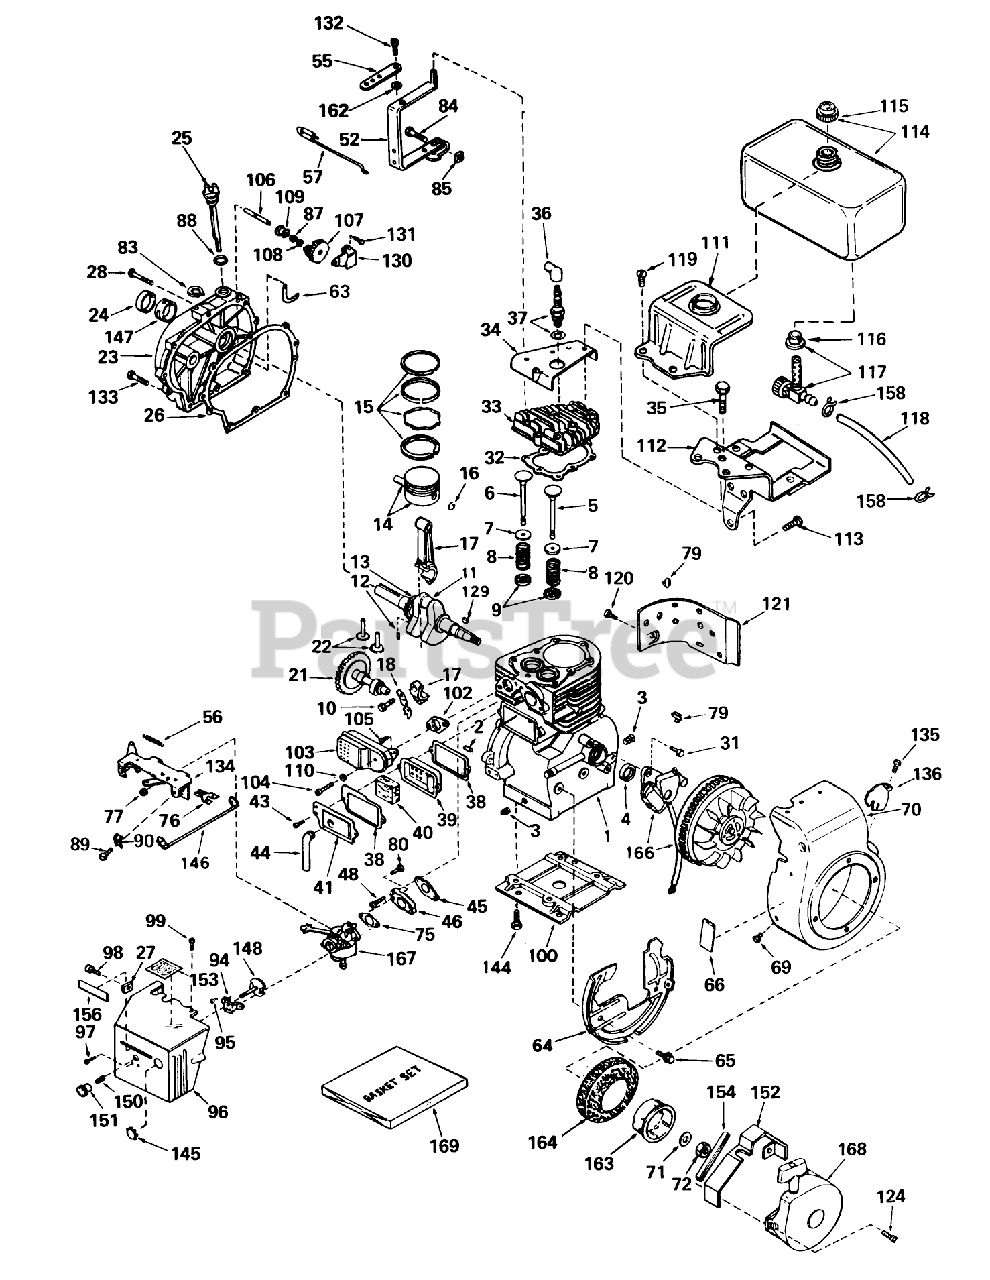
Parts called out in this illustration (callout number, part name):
1	Cylinder Assy. (Incl. Nos. 2, 3 4)
2	Pin-Dowel
3	Plug-Drain, Oil (SQH 1/4-18)
4	Oil Seal
5	Valve, Intake (Standard)(Incl. No. 9)
5	Valve, Intake (1/32" oversize)(Incl. No. 9)
6	Valve, Exhaust (Standard)(Incl. No. 9)
6	Valve, Exhaust (1/32" oversize)(Incl. No. 9)
7	Cap-Spring, Valve
8	Spring-Valve
9	Keeper-Spring, Valve
10	Screw, Hex Hd.
11	Crankshaft Assy. (Incl. Nos. 12 13)
12	Pin, Groove
13	Gear-Crankshaft
14	Piston Pin Assy. (Incl. 2 of No. 16)(Standard)
14	Piston Pin Assy. (Incl. 2 of No. 16)(.010 oversize)
14	Piston Pin Assy. (Incl. 2 of No. 16)(.020 oversize)
15	ORing
15	Ring Set (.010" OS)
15	Ring Set (.020" OS)
17	Rod Assy., Connecting (Incl. Nos. 10 18)
18	Plate, Lock
21	Camshaft
22	Lifter Valve
23	Cover, Cylinder (Incl. Nos. 24 106)
24	Oil Seal
25	Dipstick, Oil (Incl. No. 30)
26	Gasket-Cover, Cylinder
27	Nut-U Type
28	Screw (1/4-20 x 1-1/4)
31	Screw
32	Gasket-Cylinder Head
33	CYLINDER HEAD
34	Cover-Head, Cylinder
35	Screw Hex Hd. Cap
36	Cover-Spark Plug
37	Plug, Spark (J17LM or equiv.)
38	Gasket-Breather
39	Body-Breather
40	Element-Breather
41	Cover-Valve
43	Screw
44	Tube-Breather
45	Gasket-Intake
46	Flange, Carburetor (Incl. Nos. 77 80)
48	Screw
52	Lever, Governor
56	Spring, Extension
57	Link, Governor to Throttle
63	Rod, Governor
64	Baffle Blower Housing
65	Screw (1/4-20x19/32)
66	Decal, Instruction
69	Screw, Hex Hd.
70	Housing, Blower
71	Washer
75	Gasket-Carburetor
76	Terminal
77	Nut and Lock Washer (1/4-28)
79	51004 GIL ROTARY TI
80	Screw
83	Ring-Retaining
84	Screw
85	Nut-Lock
87	Washer-Flat
88	Gasket
89	Screw (10-32 x 3/8)
90	Conduit
94	Bracket-Choke
95	Screw (10-32 x 1/2)
96	Cover, Carburetor
97	Screw (8-32 X 5/16)
98	Screw (8-32 x 3/8)
99	Screw (10-32x1/2)
100	Base Engine
102	Gasket Exhaust
103	Muffler
104	Screw Hex Hd. Cap
105	Screw
106	Shaft-Governor
107	Governor Gear ASM
108	Ring-Retaining
109	Spool-Governor
110	Washer
111	Plate, Fuel Tank Mounting
112	Bracket, Fuel Tank
113	Screw (1/4-20x19/32)
114	Tank Assy., Fuel (Incl. Nos.115 117)
115	Cap, Fuel
116	Bushing, Fuel Fitting
117	Valve, Fuel Strainer Shut-off (Incl. No.116)
118	Line-Fuel
119	Screw, Fil, Slotted Hd. Sems
120	Screw
121	Emnsion, Blower Housing
124	Screw
129	Key-Flywheel
130	Bracket, Governor
131	Screw (10-32 x 35/64)
132	Screw
133	Screw
134	Bracket Assy., Speed Control (Incl. No. 56)
135	Screw, Pan Hd.
136	Screw
144	Screw
145	Plug
146	Wire, Ground
147	Bushing-Crankshaft
148	Plate, Choke
150	Spring, Compression
151	Knob, Choke
152	Guard, Starter
153	Decal, Operating
154	Seal, Snowguard
156	Decal, Choke
158	Clamp-Line, Fuel
162	Washer-Lock
163	Cup-Starter
164	Screen, Air
166	Magneto
167	Carburetor (Incl. No. 75)
168	Starter Assy., Rewind
169	Gasket Set
